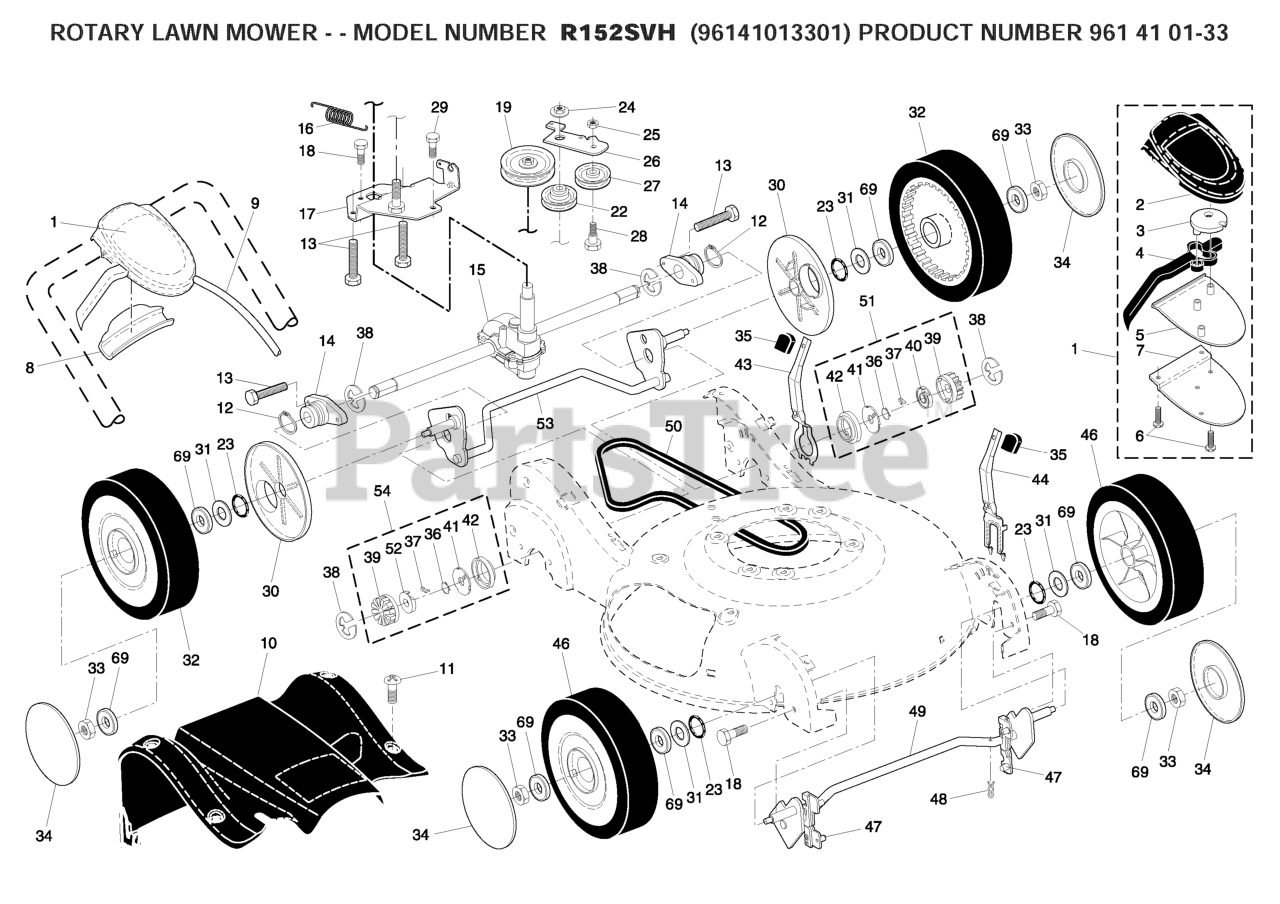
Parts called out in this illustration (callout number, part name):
1	CONTROL.DR.HV.RWGD.GRY/BLU
2	COVER TOP AUTO WALK CONTROL
3	PULLEY.CAM.DRIVE.CONTROL.HV
4	LEVER
5	COVER BOTTOM AUTO WLK CONTROL
6	SCREW, PHILLIPS HEAD 10 X 5/8
7	BRACKET.DRIVE.CONTROL.MOUNT.BL
8	EZ WALK SNAP COVER PLATE
9	ASM.CABLE.
10	COVER.DRIVE.REAR.21.HV.GRAY
12	RETAINING RING (2 2)(3 2)
13	SCREW.1/4-20X21/4.HEX.
14	BEARING / AXLE SUPPORT
15	TRANSMISSION.21.RWGD.HV
17	BRACKET, GEAR CASE / DRIVE
19	RP PULLEY.DRIVE.EZ
22	PULLEY.IDLER.V-BELT
23	O-RING..070X.487.NEOPRENE
24	NUT.HEX.FLANGE.3/8-16.LOCKNUT
25	NUT.CENTERLOCK.5/16-
26	ARM.IDLER.BZP
27	IDLER PULLEY
28	SHOULDER BOLT
29	SCREW 14-20 X 5/8
30	DUST COVER, WHEEL
31	WASHER.FLAT.1/2
32	WHEEL.9X2.25.LP.TIGER.BLACK
33	NUT.HEX.FLANGE.3/8-16.LO(3 2)
34	HUBCAP.WHEEL.5.SPOKE.SILVER
35	KNOB.SELECTOR.SPRG.H-GRY (2 2)
36	SPRING, TORSION
37	PAWL.DRIVE.21.EZ-WALK
38	E-RING 7/16 RE
39	GEAR, PINION
40	RETAINER.DRIVE.21.EZ-WALK.LT
41	DISC.DRIVE.21.EZ-WALK
42	SEAL.PINION
43	LEVER, SELECTOR, HEIGHT, REAR
44	LEVER, SELECTOR, HEIGHT, FRONT
46	WHEEL.9X2.25.LP.TIGER.BLK
47	BUSHING.FRONT.TORQUE.SHAFT
48	SPRING RETAINER
49	SHAFT FRONT
50	BELT, DRIVE
52	RETAINER, DRIVE, RH
53	SHAFT.ASM.REAR.TORQUE.HV.BZP
69	BEARING.8".WHEEL
